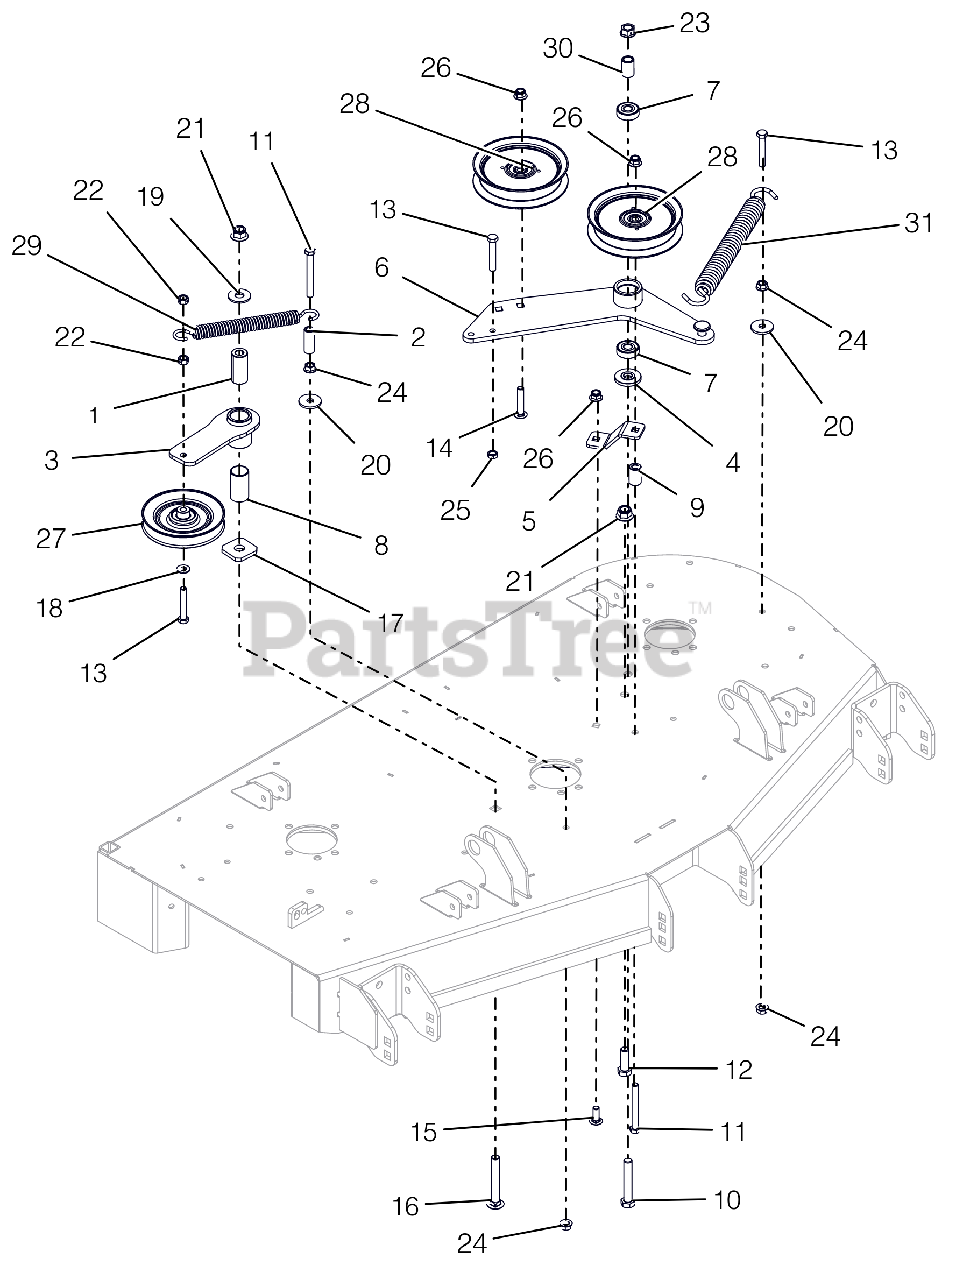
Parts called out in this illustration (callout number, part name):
1	BSHG, SPCR .502X.997X2.03 PM
2	SPACER, .375IDX.625ODX1.66 PM
3	WMT, IDLER ARM - BLACK
4	SPACER, IDLER ARM
5	PTO FIXED IDLER MTG BRKT-ORG
6	DECK PTO IDLER ARM WLDMT - BLK
7	BRG-BALL .500X1.38X.437
8	BSHG, 1.00X1.125X1.937
9	BUSHING, SLV .380X.750X1.190
10	@BLT-HEX .50-13X3.00 GR5 YWZC
11	@BLT-HEX .38-16X3.25 GR5 YWZC
12	@BLT-HEX .50-13X1.50 GR5 YWZC
13	@BLT-HEX .38-16X2.25 GR5 YWZC
14	BLT-RDHDSQNK .38-16X2.00 SHTYW
15	@BLT-RDHDSHSQNK.38-16X1.0 G5YZ
16	@BLT-RDHDSQNK .50-13X3.50 G5YZ
17	WSHR-FLT .640X1.75X.250
18	@WSHR-FL-STL.406X.812X.065 YWZ
19	@WSHR-FL-STL.563X1.38X.109YWZC
20	WSHR-FL-STL .406X1.375X.135 YZ
21	@NUT-LK-NYL-FLG .50-13 YWZC
22	@NUT-LK-CTR .38-16 YWZC
23	NUT-LK-CTR-FLG .50-13 YWZC
24	@NUT-SPNLK-FLG .375-16 YWZC
25	NUT-HEX-JAM .375-16 YWZC
26	@NUT-LK-NYL-FLG .38-16 YWZC
27	IDLER, V-5.00"
28	IDLER, FLAT 5.00"
29	SPRING, EXTENSION
30	SPACER .510 X .75 X 1.1485
31	SPRING, EXTENSION
